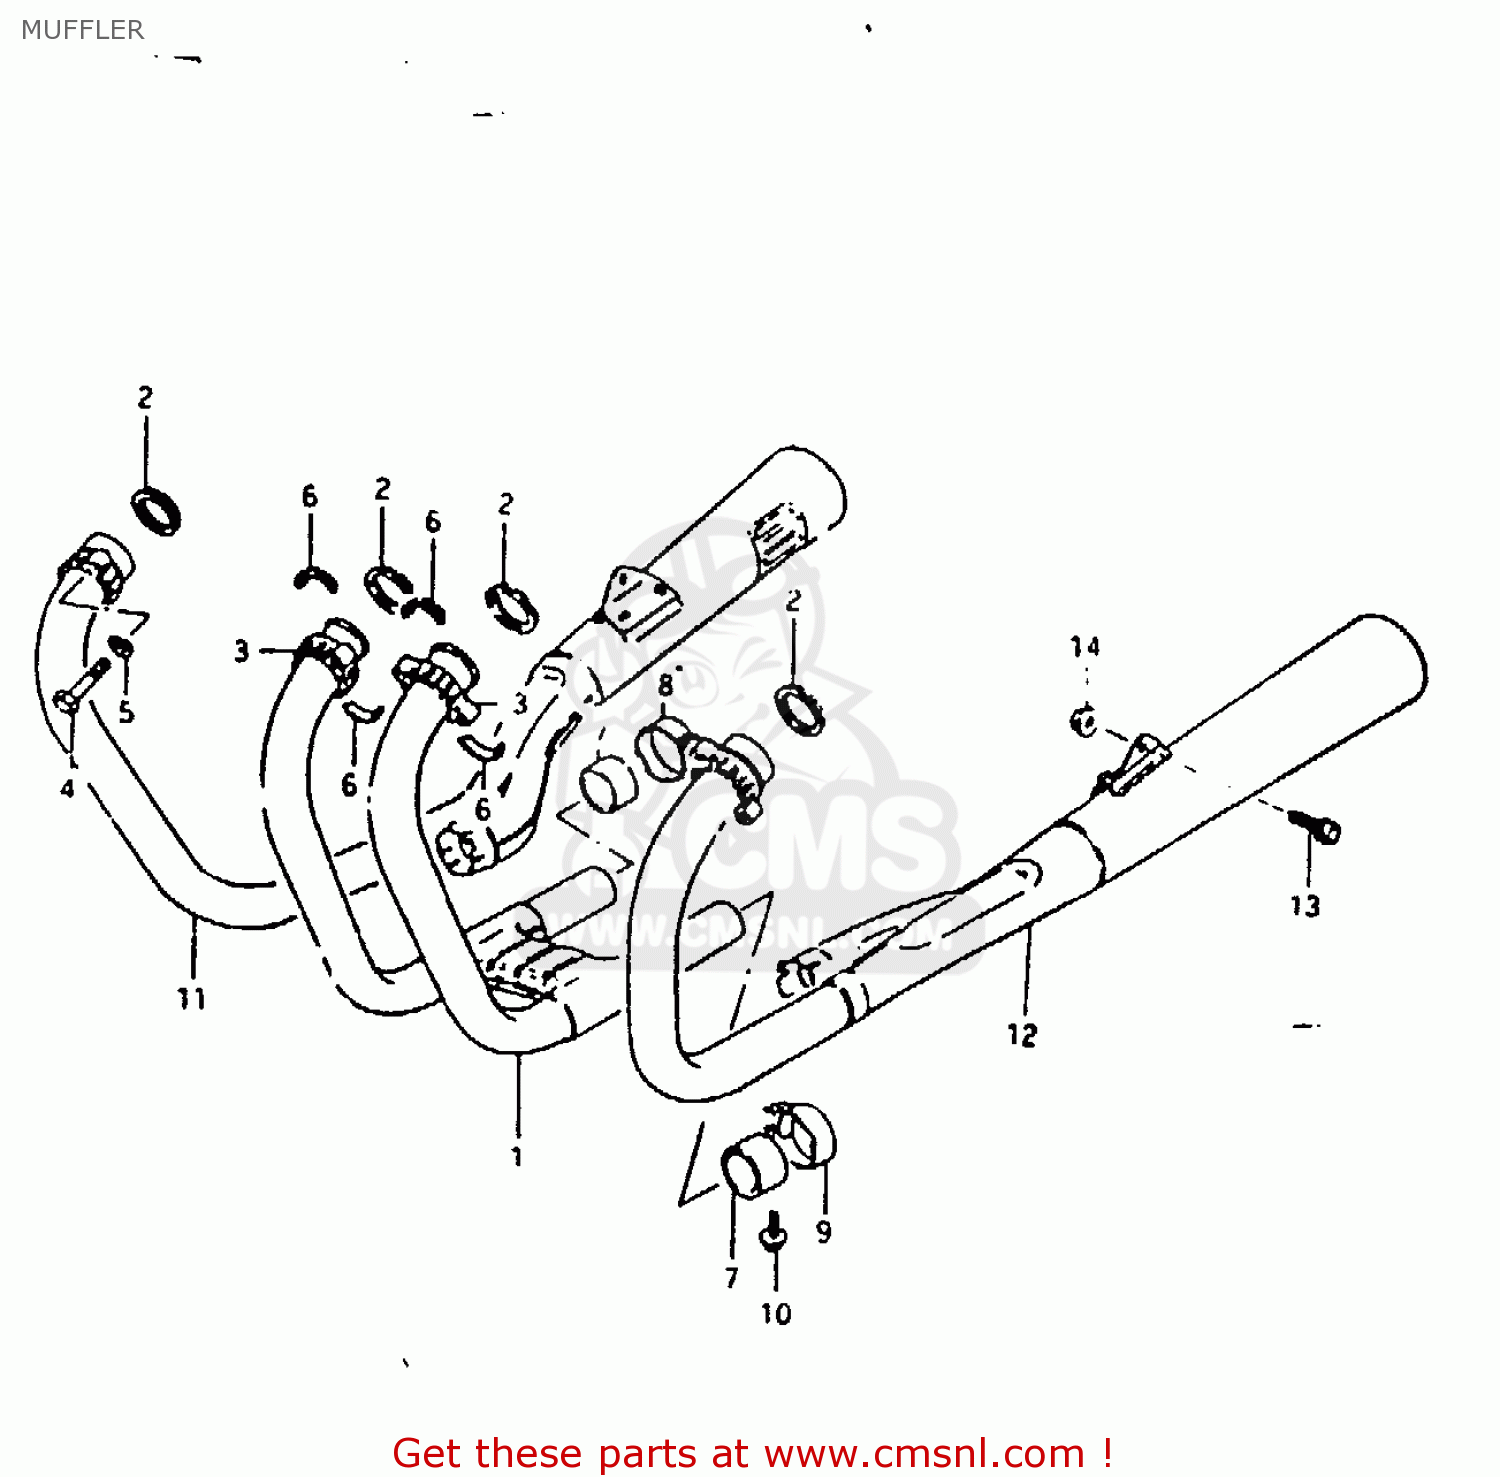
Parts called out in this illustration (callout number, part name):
1	PIPE,EXHAUST
2	GASKET,EXHAUST PIPE (NAS)
3	CLAMP,EXHAUST PIPE
4	BOLT
5	LOCK WASHER
6	PLATE,EXHAUST P
7	CONNECTOR,MUFFLER
8	CLAMP,MUFFLER CONNECTOR,R
9	CLAMP,MUFFLER CONNECTOR,L
10	BOLT
11	MUFFLER, RH
12	MUFFLER, LH
13	BOLT
14	NUT
